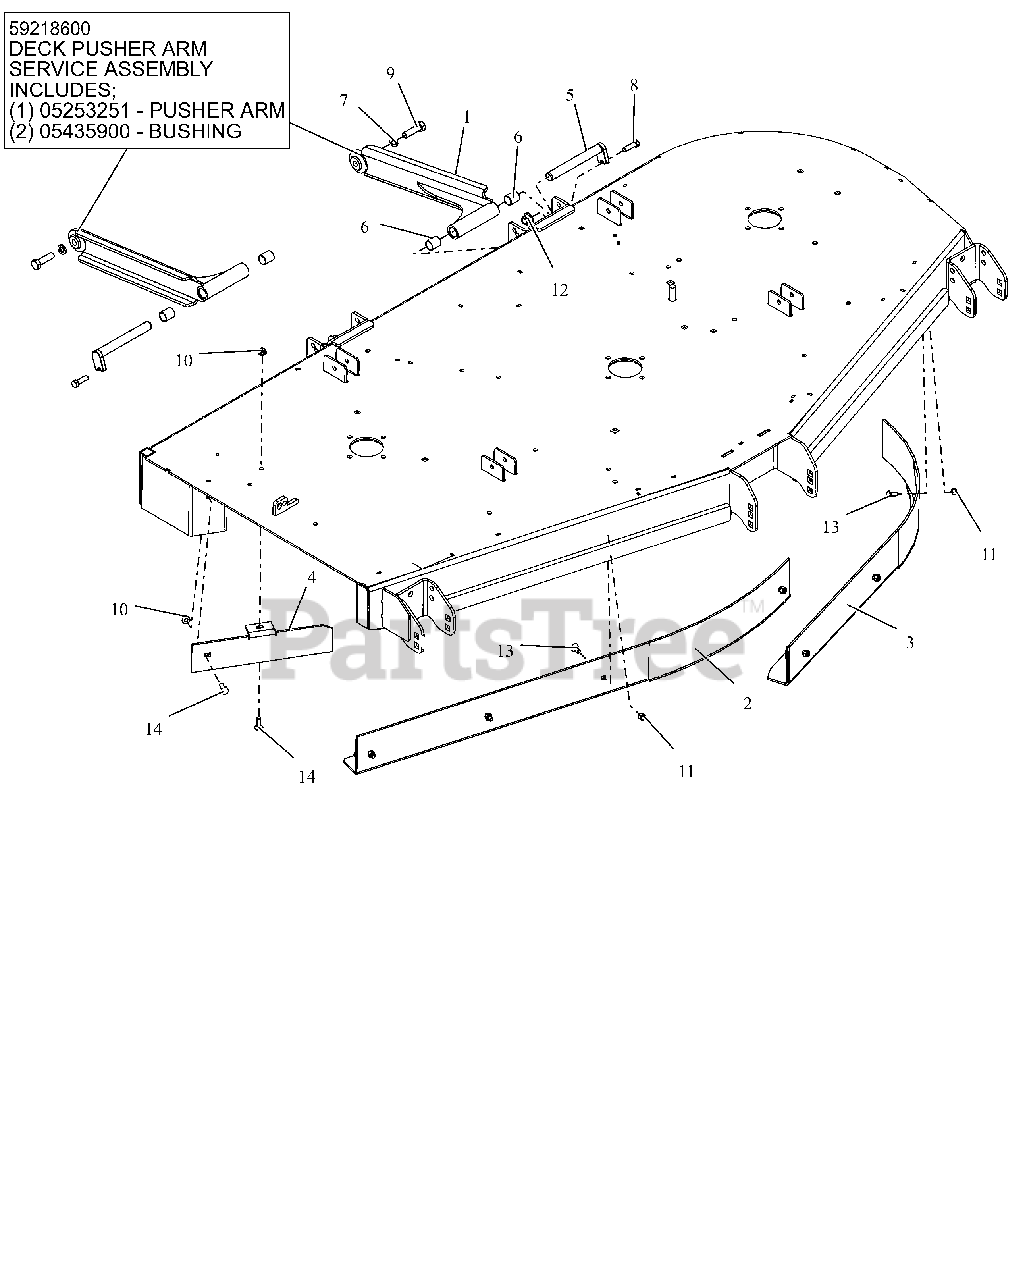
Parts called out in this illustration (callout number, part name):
1	WLDMT, DECK STABILIZER ARM (BLACK)
1	DECK STABILIZER ARM W/BUSHINGS
2	WLDMT, 72" RH VACUUM BAFFLE (RED)
3	WLDMT, 72" LH VACUUM BAFFLE (RED)
4	72" DISCHARGE BAFFLE - RED
5	PIN, MOWER MTG
6	BRG, .750 X .875 X 1.000
7	WSHR,LK-REG .500X.125 ZCC
8	BLT, HEX .38-16X1.25 G5 ZCC
9	BLT, HEX 0.5-13X1.75 GR5 ZCC EP80
10	NUT,NYL-FLG .31-18 GF ZCC
11	NUT,NYL .31-18 G5 ZCC
12	NUT,NYL-FLG .50-13 GF ZCC
13	BLT,RHSN .31-18X.75 G5 ZCC
14	BLT,RHSN .31-18X1.00 G5 ZCC
